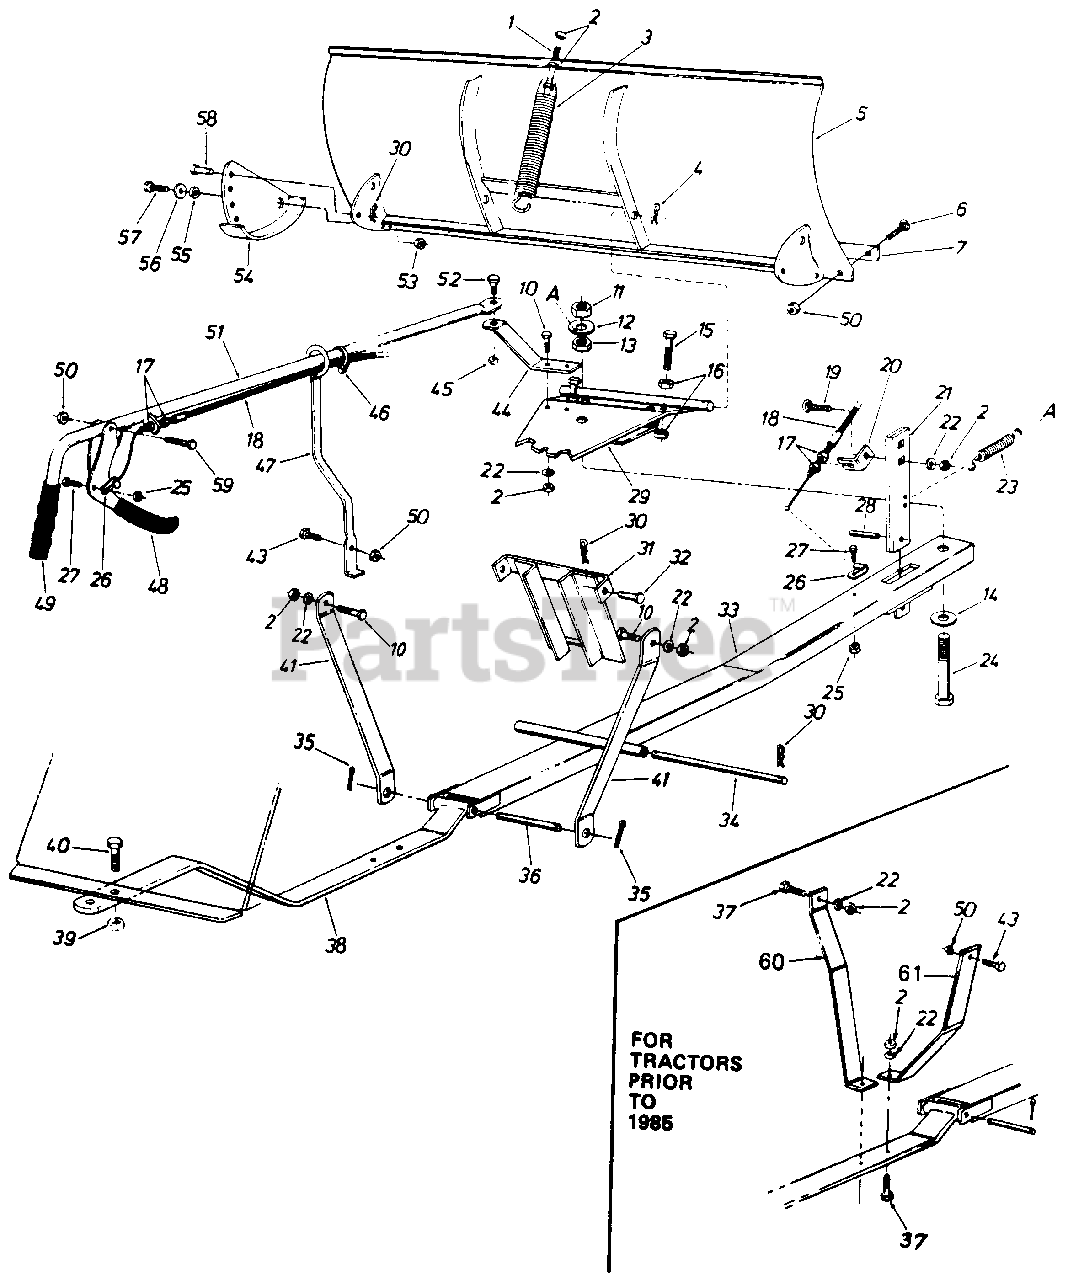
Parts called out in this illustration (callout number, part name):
1	Hex Scr. 3/8-16 x 4. 50" Lg.
2	Hex Nut 3/8-16 Thd.
3	Blade Adjustment Spring
4	Hairpin Clip 5/32" Dia.
5	48" Blade Ass'y.
6	Carriage Bolt 5/16-18 x .75" Lg.
7	Wear Plate 48"
10	Hex Scr. 3/8-16 x 1..00" Lg.
11	Hex L.-Nut 3/4-10 Thd.
12	Fl.-Wash..810" I.0. x 2.00" O.D.
13	Hex Jam Nut 3/4-10 Thd.
14	Fl.-Wash..810" I.0. x 2.00" O.D.
15	Hex Scr. 1/2-13 x 2.00" Lg.
16	Hex Nut 1/2-13 Thd.
17	Hex Jam Nut 5/16-24 Thd.
18	Control Cable Ass'y.
19	Carriage Bolt 3/8-16 x 1.25" Lg.
20	Cable Guide Bracket
21	Angle - Lock Bar
22	L.-Wash. 3/8" I.D.
23	Angle Lock Spring
24	Hex Scr. 3/4-10 x 4.00" Lg.
25	Hex L-Nut 1/4-20 Thd.
26	Clevis Lanyard Fitting
27	Hex Scr. 1/4-20 x 75" Lg
28	Roll Pin 1/4" Dia. x 1.00" Lg.
29	Pivot Plate Ass'y.
31	Guide Bracket Ass'y.
32	Clevis Pin 1 2" Dia. x 1.00" Lg.
33	Push Bar Ass'y.
34	Lift Shaft
35	Cotter Pin 5 32" Dia. x 1.00" Lg.
36	Pivot Shaft
37	Hex Scr. 3/8 16 x 1.25" Lg.
38	Hanger Bracket Ass'y.
39	Hex L.-Nut 5/8-11 Thd.
40	Hex Scr. 5/8-11 x 1. 50" Lg.
41	Hanger Link
43	Hex Bolt 5/16-18 x 100" Lg
44	Blade Pivot Bracket
45	Hex L.-Nut 3/8-16 Thd.
46	Nylon Cable Tie
47	Tube Guide Ass'y.
48	Clutch Grip Ass'y.
49	Grip-3/4" Handle
50	Hex L-Nut 5/16-18 Thd.
51	Tube Handle Ass'y.
52	Shld. Scr: Special 3/8-16 Thd.
53	Hex L.-Nut 3/8-16 Thd.
54	Skid Assembly
55	Spacer
56	Fl.-Wash..385" I.D. x 1.00" O.D.
57	Hex Scr. 3/8-16 x4 .75" Lg.
58	Clevis Pin 5/16" Dia. x .75" Lg.
59	Hex Scr. S/16-18 x 1,50" Lg.
60	Mounting Brkt.-L.H.
61	Mounting Brkt-R.H.
